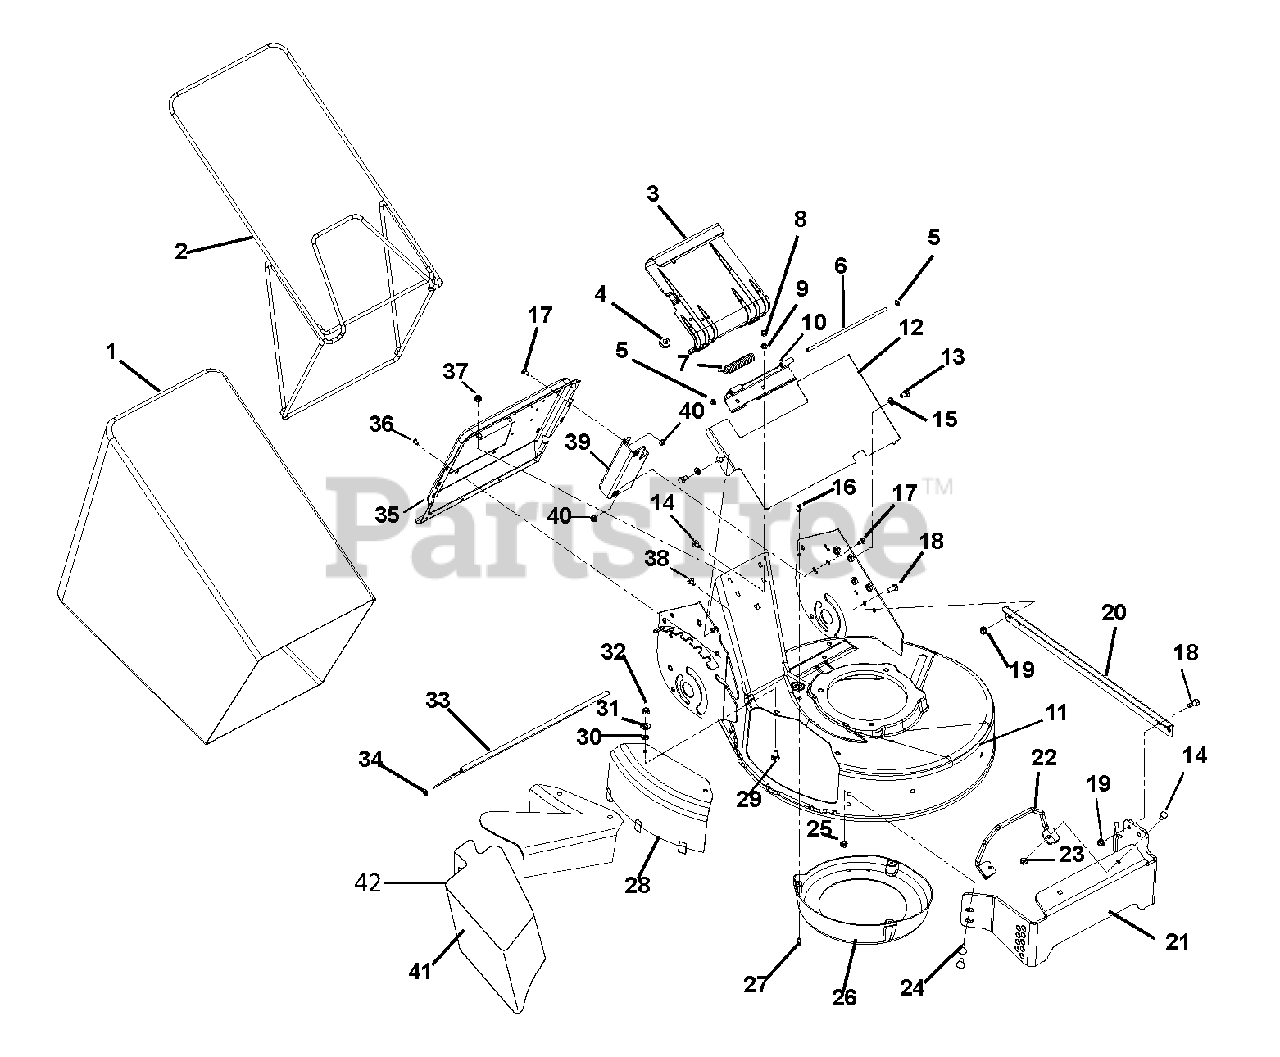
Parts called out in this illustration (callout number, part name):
1	Bag, Consumer Black 15 OZ/YD2
2	Frame, WBLM Bagger
3	Catcher Plate Door
4	Button Bumper
5	Push Nut, .25
6	Door Pin
7	Spring, Torsion .120 x .68 x 3.09
8	Nut, Hex .25-20
9	Washer, Locking .250 x .077 Heavy
10	Hinge
11	Chassis, Pro 21 XD
12	Grill Insert
13	Screw, Tapping .250-20 x .37 Hex Washer Head
14	Bolt, Round Head Square Neck .25-20 x .75
15	Washer, Locking .31 x .078 Regular
16	Plastic Grommet
17	Bolt, Round Head Square Neck .25-20 x .50 Grade 5
18	Bolt, Hex .31-18 x .75 Grade 5
19	Nut, Locking-Top-Flange .31-18
20	Angle, Support
21	Bumper, Pro 21"
22	Angle, Support
23	Nut, Locking-Top-Flange .25-20
24	Bolt, Round Head Square Neck .31-18 x .75 Grade 5
25	Nut, Spin Lock-Flange .312-18
26	Center Baffle
27	Screw, Tapping 10-16 x .62 SLPH AB
28	Cover, Side Discharge
29	Bolt, Round Head Square Neck .31-18 x .75 Grade 2
30	Nut-Push .312
31	Washer, Flat-Steel .406 x .812 x .065
32	Nut, Locking-Nylon .312-18
33	Trailing Shield
34	Nut, Push .312
35	Catcher Plate
36	Screw, Tapping 10-24 x .375 TORX Pan Head
37	Nut, Locking-Flange .250-20
38	Bolt, Round Head Square Neck .25-20 x .50 Grade 5
39	Bracket, Bagger Support
40	Nut, Locking-Flange .250-20
41	Plug, Mulchmaster Mulcher
42	Side Discharge Assembly
